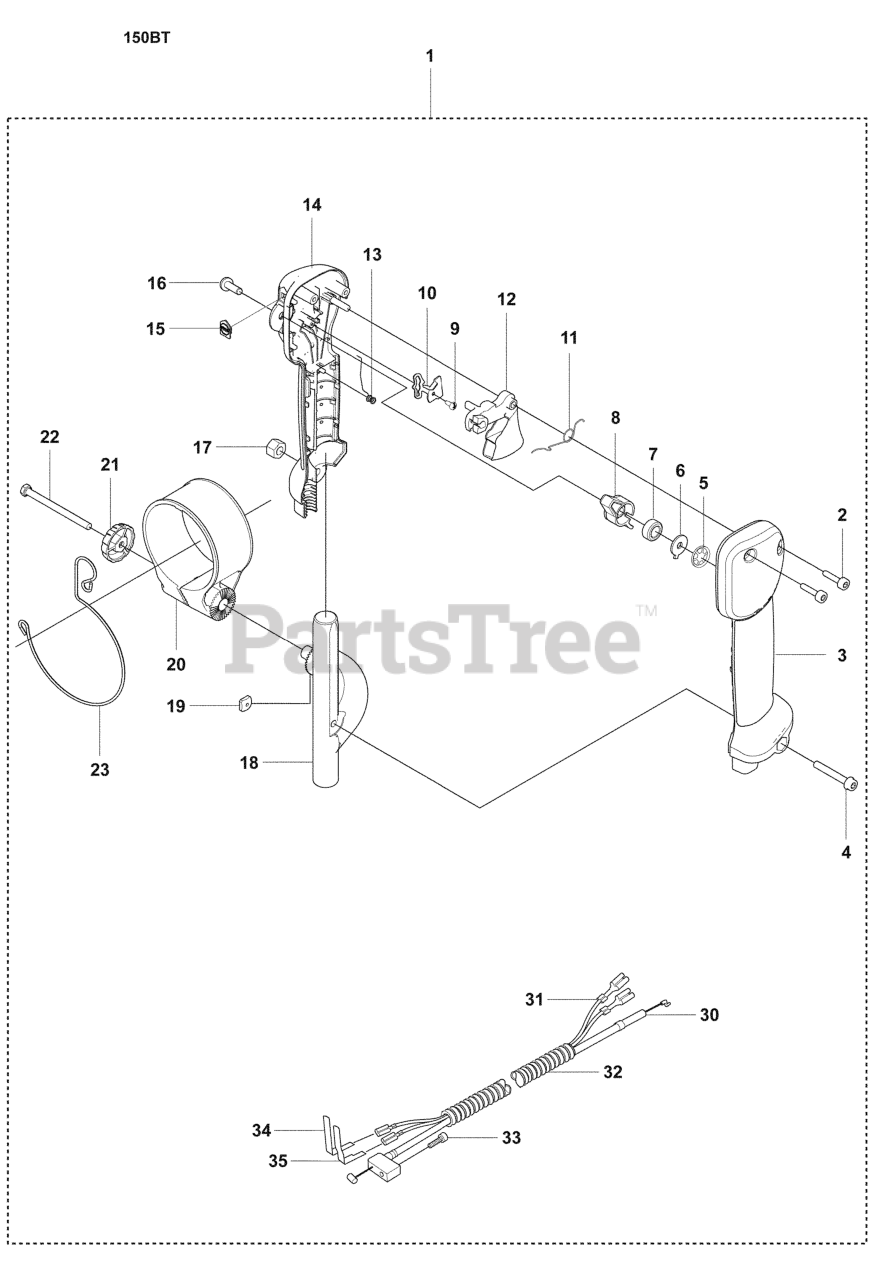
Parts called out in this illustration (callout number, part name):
1	HANDLE ASSY 150BT
3	HANDLE HALF (R)
4	SCREW
7	SPRING RUBBER
8	LEVER STOP
12	TRIGGER 848L5W34C0
14	HANDLE HALF (L)
18	HOLDER, HANDLE
20	HOLDER TH
21	KNOB
30	CABLE COMP
31	RP CORD
34	CONTACT SPRING
35	CONTACT SPRING
